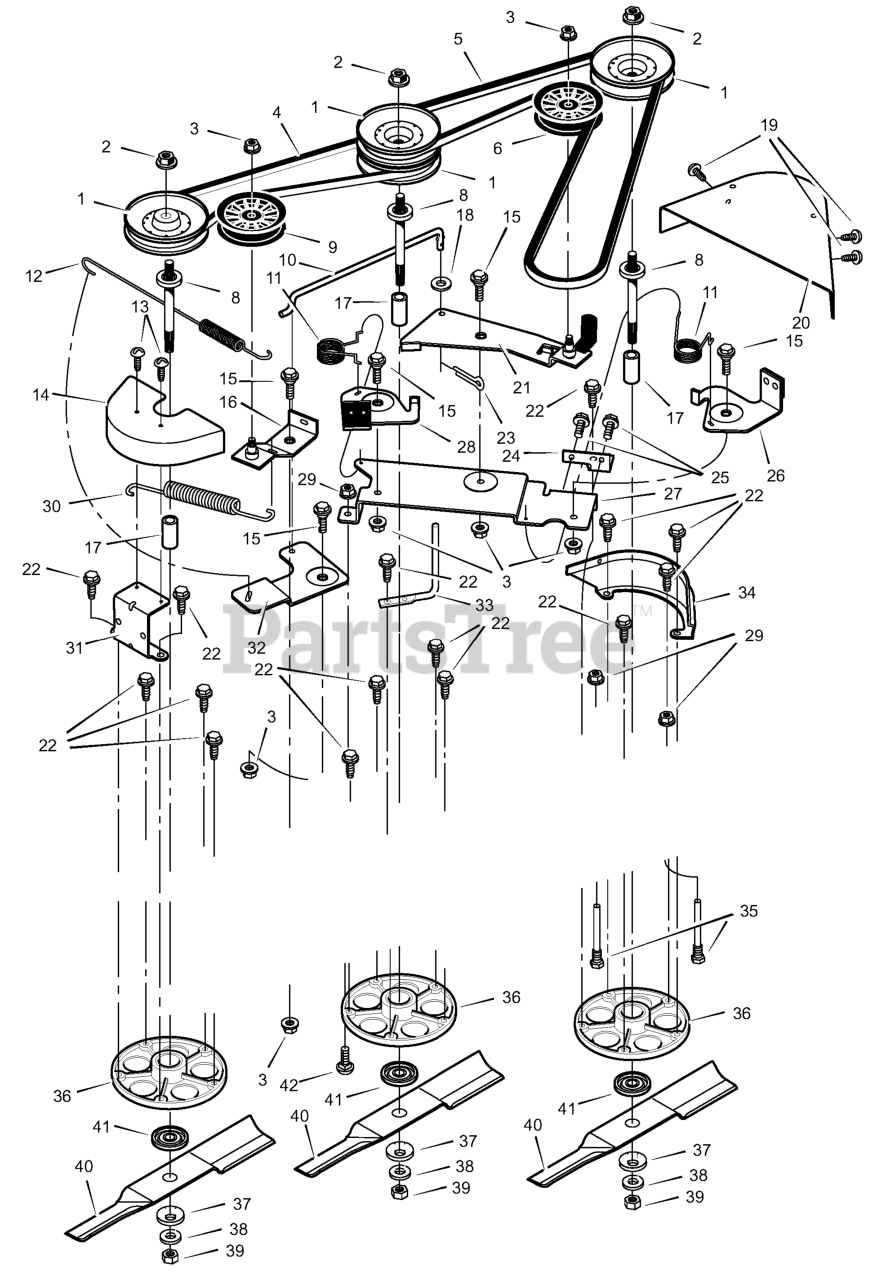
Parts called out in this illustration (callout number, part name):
1	Pulley
3	Nut
4	Belt, Secondary
5	Belt, Primary
6	Pulley, Idler
8	Jackshaft
9	Pulley, Idler
10	Link, Bell Crank
13	Screw
14	Cover, Right Pulley
15	Bolt, Shoulder
16	Arm Assembly, Idler
18	Washer
20	Cover, Left Pulley
21	Arm Assembly, Idler
22	Bolt
23	Pin, Cotter
24	Bracket, Brake Plate
26	Brake Assembly, Left
27	Plate, Brake Arm
28	Brake Assembly, Center
29	Nut, Flange
31	Bracket, Cover
32	Bell Crank
33	Guide, Belt
34	Bracket, Pulley Cover
35	Guide, Belt
36	Housing, Jackshaft
39	Nut, Blade
41	Adapter, Blade
42	Bolt, Carriage
